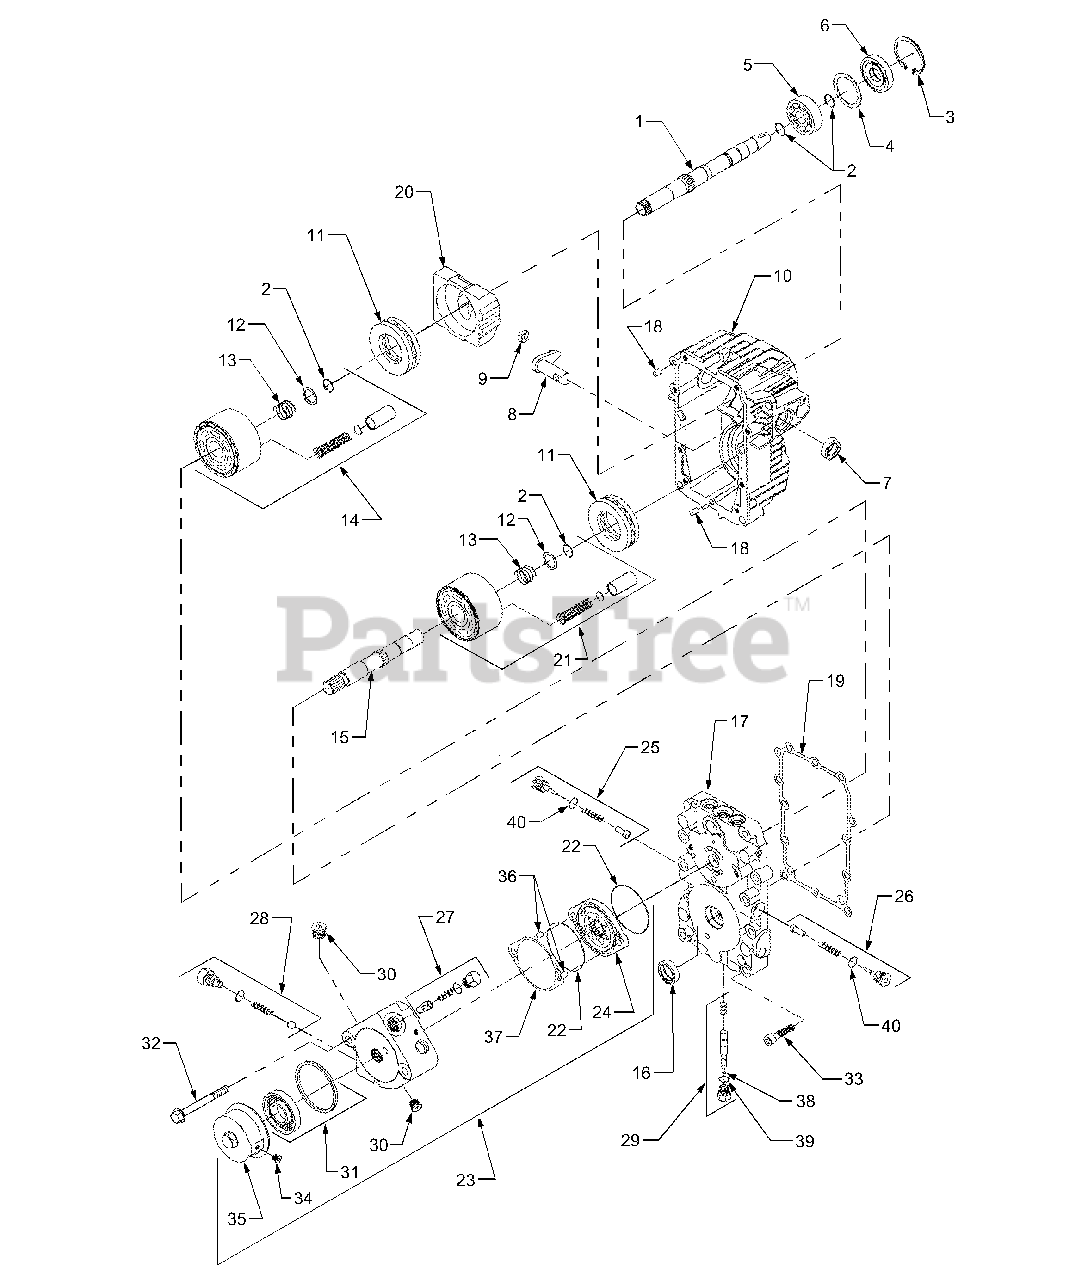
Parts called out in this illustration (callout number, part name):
1	Shaft, Pump
2	Ring, Wire Retaining
3	Ring, Retaining
5	Bearing, Ball
6	Seal, Lip
8	Arm, Trunnion
9	Guide, Slot
10	Housing Assembly
11	Bearing Assembly, Thrust Ball
12	Washer, Block Thrust
13	Spring, Block
14	Kit, Pump Cylinder Block
15	Shaft, Motor
16	Not Used In This Application
17	Kit, Center Section
19	Gasket, Center Section
20	Swashplate, Variable
21	Kit, Motor Cylinder Block
23	Kit, Auxiliary Charge Pump
24	Gerotor & Housing Assembly
25	Kit, Check Valve
26	Kit, Check Valve w/ .044 Orifice
27	Kit, Check Relief
28	Kit, Auxiliary Relief Valve
29	Kit, Bypass Valve
31	Kit, Auxliary Filter
32	Screw, Flange Head Cap, M8 x 60
33	Screw, Socket Head Cap
35	Cover, Filter
37	Shim, Charge Pump
38	O-Ring
39	O-Ring
40	O-Ring
